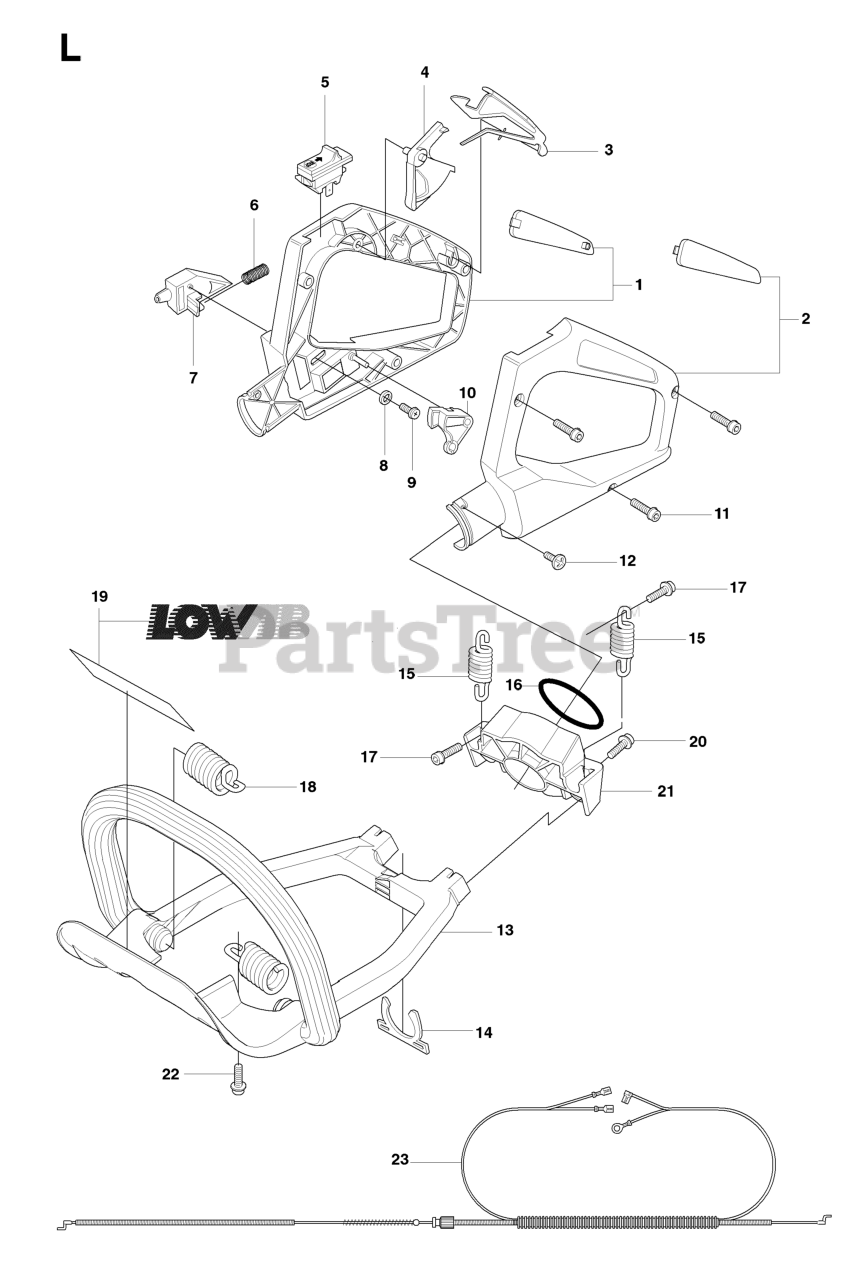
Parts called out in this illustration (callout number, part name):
1	HANDLE PART
2	HANDLE PART
3	THROTTLE LOCK
4	THROTTLE TRIGGER
5	STOP BUTTON
15	VIBRATION ABSORBER
18	VIBRATION ABSORBER
